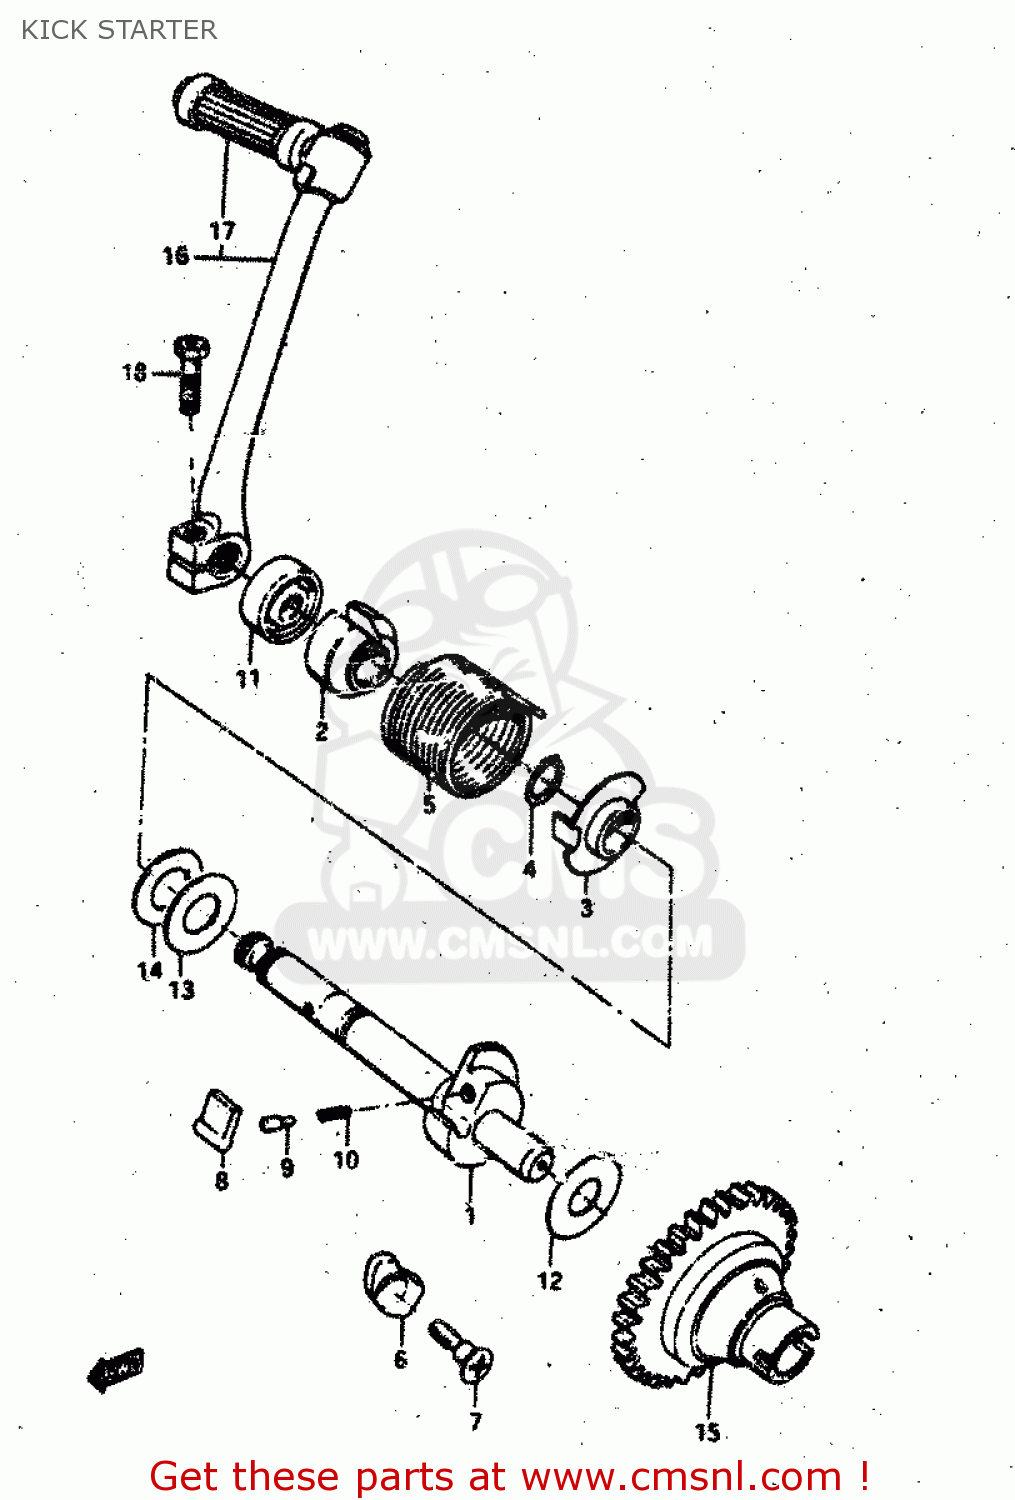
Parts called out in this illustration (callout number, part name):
1	SHAFT,KICK STARTER
2	GUIDE,KICK SHAFT SPRING
3	HOLDER,KICK STARTER SHAFT SPR
4	CIRCLIP
5	SPRING
6	LIFTER,KICK STARTER PAWL
7	SCREW(6X19)
8	PAWL,KICK STARTER
9	PIN
10	SPRING
11	SEAL,OIL(14X24X6)
12	WASHER
13	WASHER(14X29X0.8)
14	WASHER
15	GEAR,KICK STARTER DRIVE(NT:33)
16	LEVER ASSY, KICK STARTER
17	RUBBER,KICK STARTER PEDAL
18	BOLT
